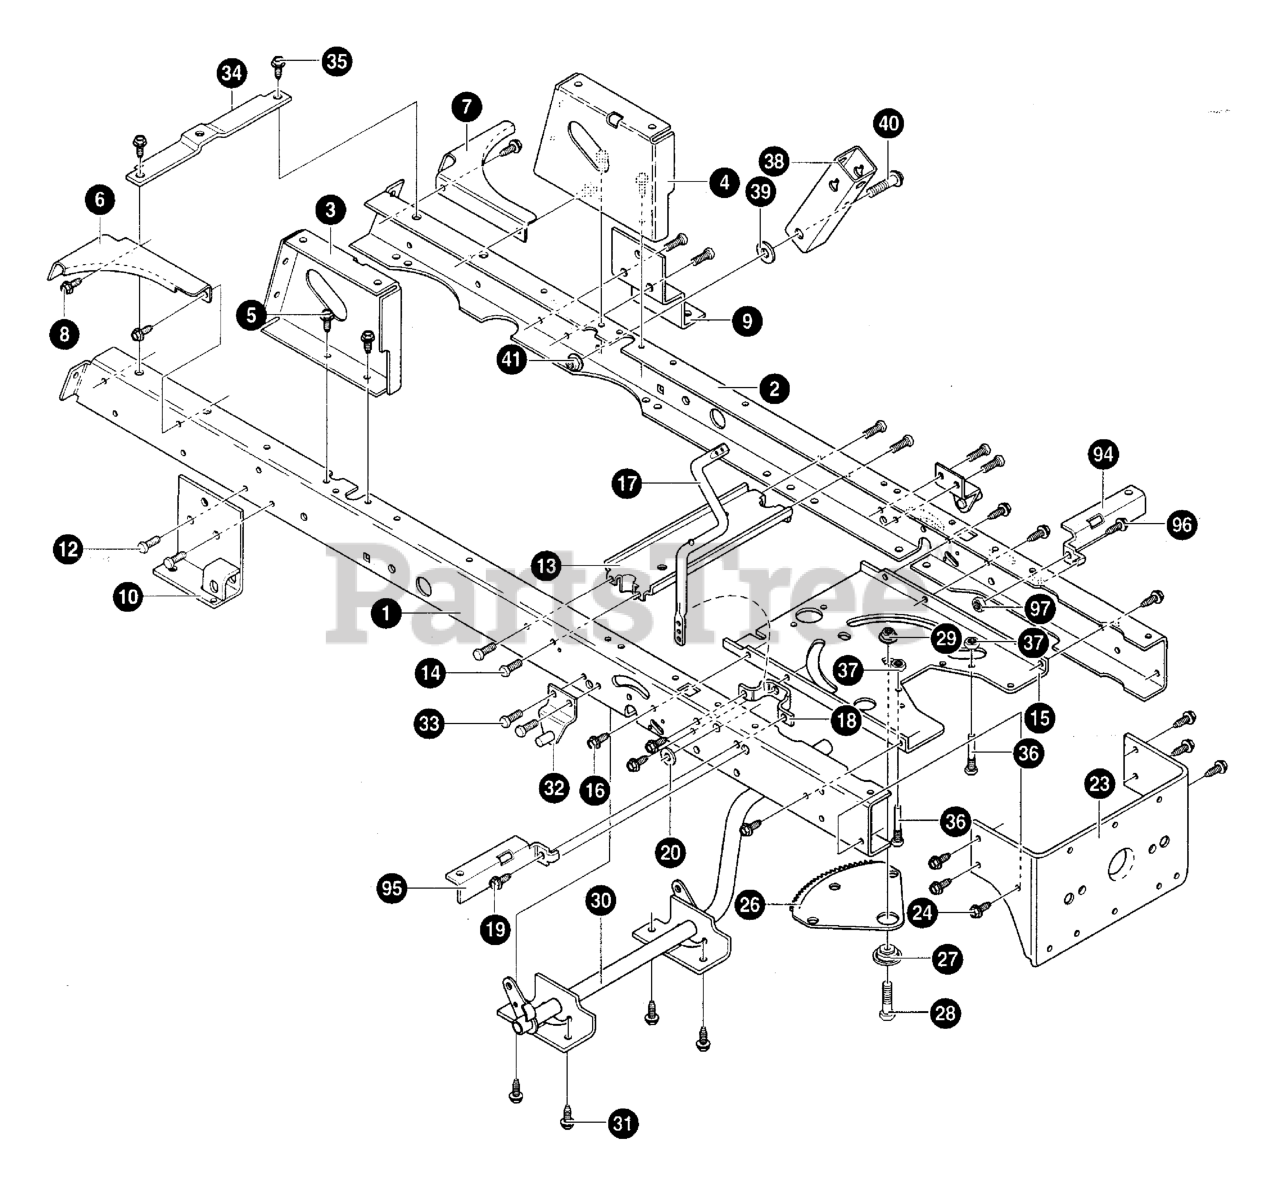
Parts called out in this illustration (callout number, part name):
1	FRAME, RAIL RH
2	FRAME, RAIL LH
3	SUPPORT, SEAT RH
4	SUPPORT, SEAT LH
5	SCREW 5/16-18X.75 HHWATAP
6	BRACE, BACKPLATE RH
7	BRACE, BACKPLATE LH
8	SCREW 51/61-8X.75 HHWATAP
9	BRACKET, TRANSAXLE
10	WELD, ASSY SHIFT BRACE LEVER
12	SCREW, 5/16-18 x 0.75 HHWATAP
13	ASM. IDLER MOUNT, FRONT
14	SCREW, 5/16-18 x 0.75 HHWATAP
15	PLATE, STEERING MOUNTING
16	SCREW, 5/16-18 x 0.75 HHWATAP
17	CRANK, PTO
18	BRACKET, BELL CRANK
19	SCREW, 5/16-18 x 0.75 HHWATAP
20	WASHER, FLAT .469X.92X.065
23	BRACKET, HANGER REAR
24	SCREW, 5/16-18 x .75 HHWATAP
26	GEAR, SECTOR
27	BEARING, SECTOR GEAR
28	SCREW, 5/16-18 x 1.00
29	NUT, 5/16-18 HEXKEPS 15X113
30	ASM., CLUTCH/BRAKE PEDAL
31	SCREW, 5/16-18 x 0.75 HHWATAP
32	BRACKET, SUSPENSION ASM.
33	SCREW, 5/16-18 x 0.75 HHWATAP
34	BRACE, RAIL
35	SCREW, 5/16-18 x 0.75 HHWATAP
36	ZINC SCREW GUIDE
37	NUT, 5/16-18 HEXWDFLLK WHIZ
38	BRACKET, PIVOT
39	WASHER, FLAT .390X1.25X.119
40	BOLT, .562X1.563 HHSH 3/8-16
41	NUT, 3/8-16 HWDFLLK MACK 15X84
94	BRACKET -SEAT DECK LH
95	BRACKET-SEAT DECK RH
96	SCREW, 5/16-18 x 0.75 HHWATAP
97	NUT, 5/16-18 HEXWDFLLK WHIZ
